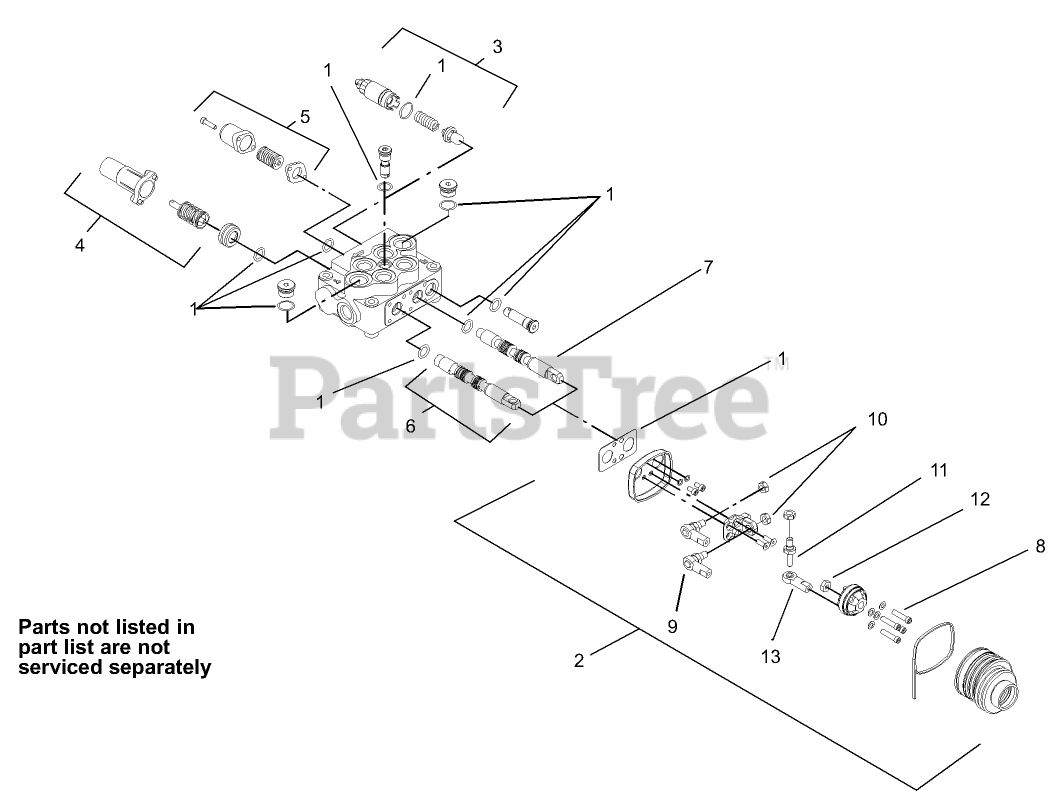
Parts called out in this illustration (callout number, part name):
1	SEAL KIT
2	JOYSTICK KIT
3	VALVE-RELIEF
4	Kit-Spring, Valve
5	Kit-Spring
8	Screw-Joystick
9	Joint-Articulated
10	Nut-Joystick
11	Pin-Joystick
12	NUT-GALVANISED
13	End-Rod
